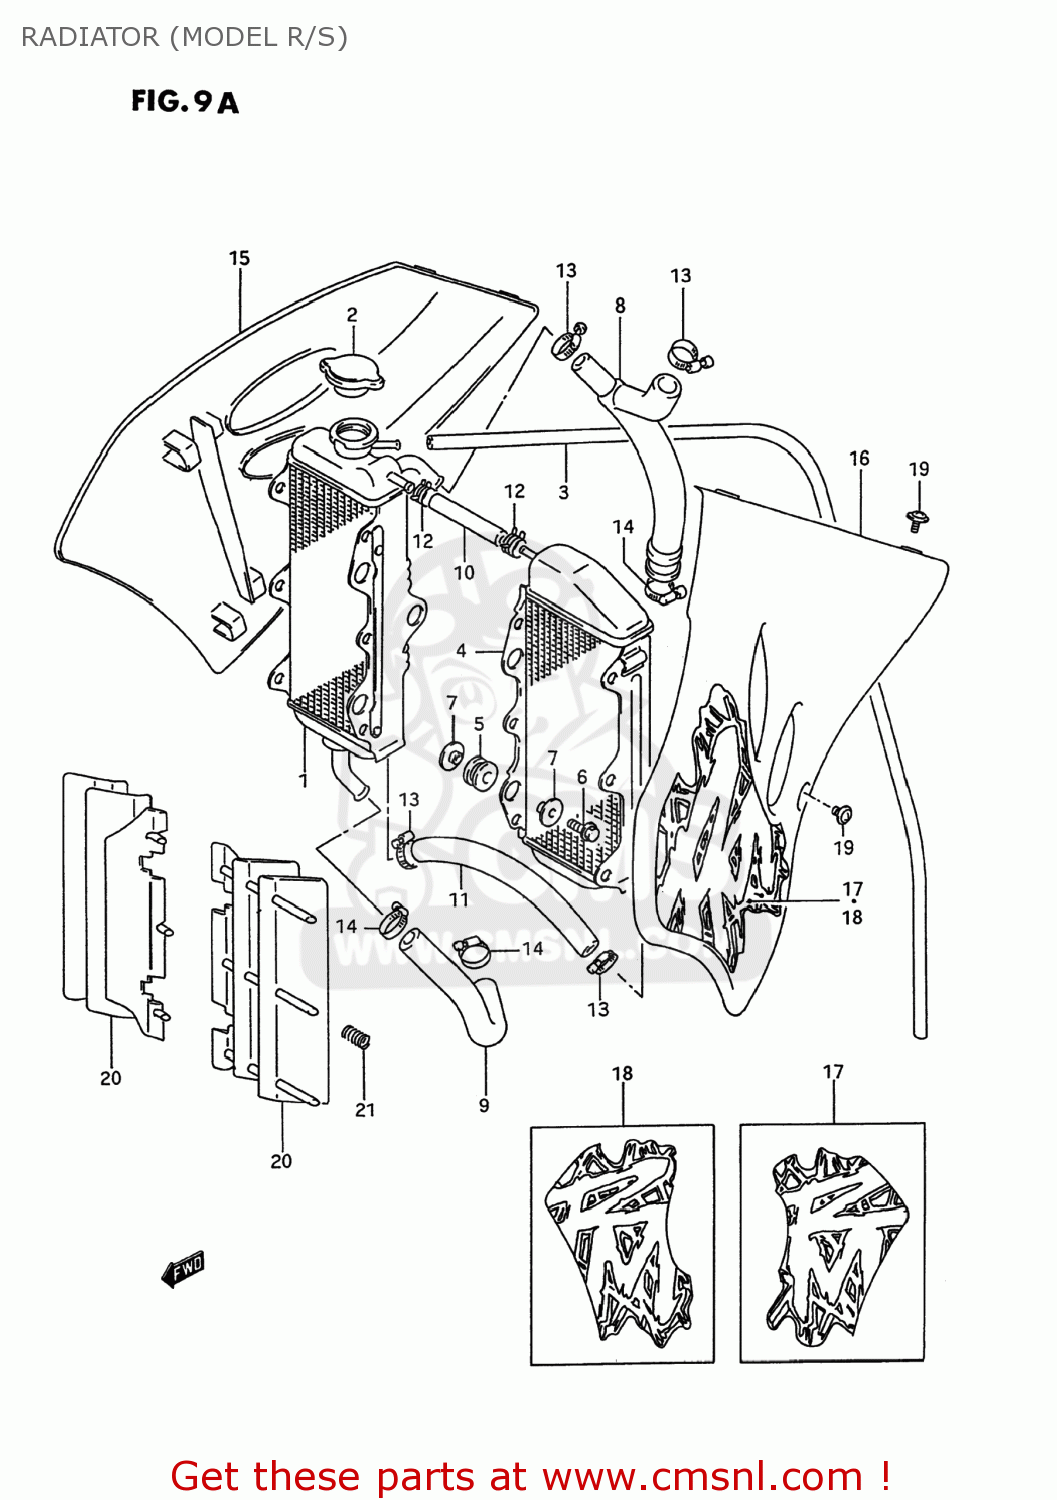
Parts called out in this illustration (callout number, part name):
1	RADIATOR,WATER,R
2	CAP,RADIATOR
3	HOSE(5X8X2000)
4	RADIATOR,WATER,L
5	CUSHION,RADIATOR LWR
6	SCREW
7	WASHER,RDTR SPRT
8	HOSE,RADIATOR INLET
9	HOSE,RADIATOR OUTLET
10	HOSE,WATER
11	HOSE,RADIATOR JOINT NO.2
12	CLIP
13	CLAMP
14	CLAMP
15	COVER,RADIATOR,R
16	COVER,RADIATOR,L
17	EMBLEM,RADIATOR COVER
18	EMBLEM,RADIATOR COVER
19	SCREW(6X12)
20	LOUVER,RADIATOR
21	SPRING
